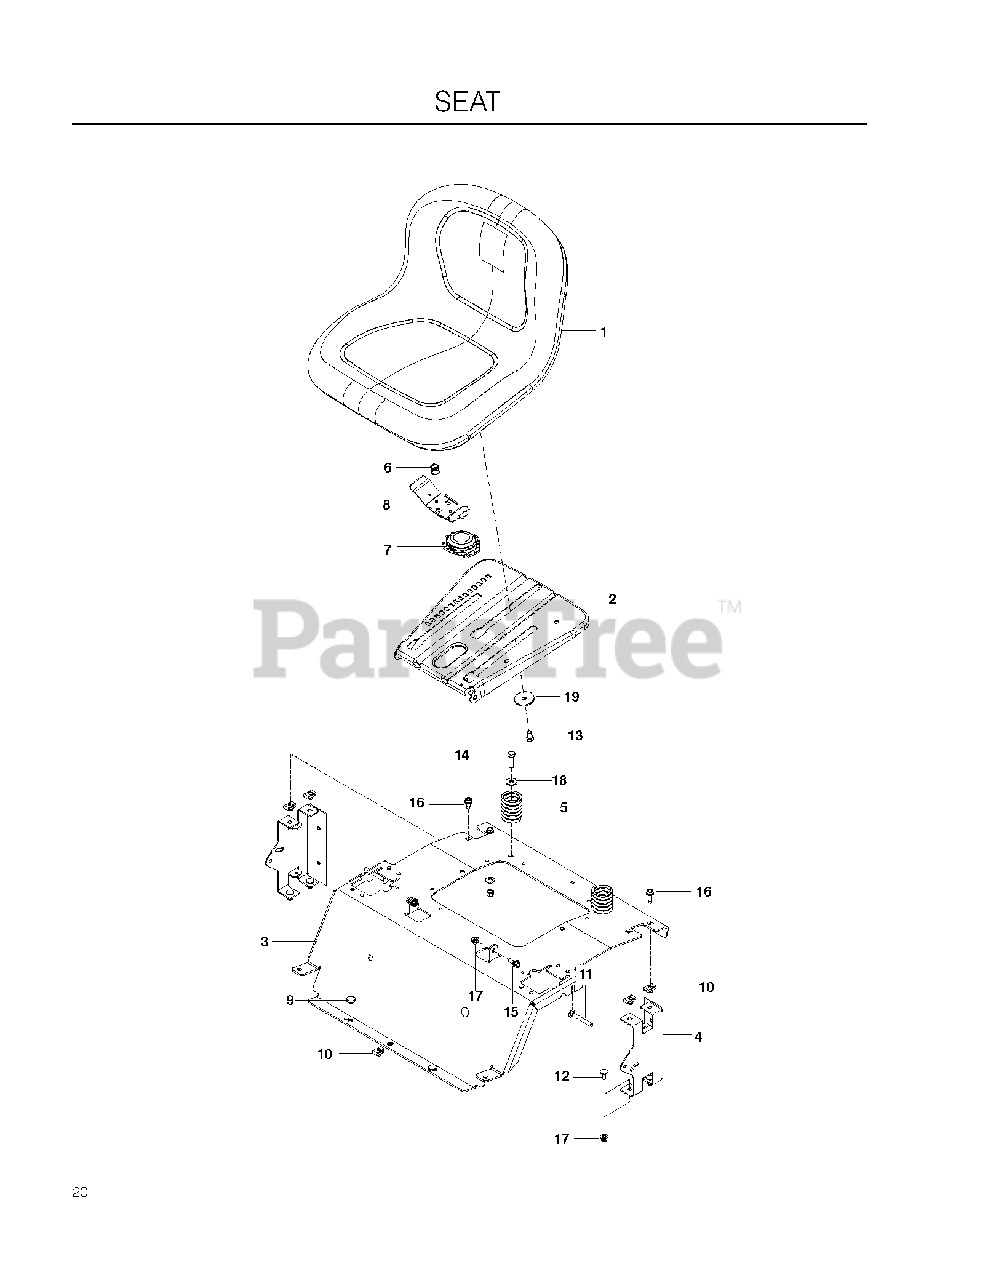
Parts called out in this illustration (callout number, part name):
1	RP SEAT, TH150, GREY, MILSCO
2	PAN.ASM.SEAT.3PT
3	SUPPORT SEAT ORANGE
4	SUPPORT, REAR SEAT, BLACK
5	SPRING, SEAT
6	SPRING.LATCH.SEAT.TEX
7	SWITCH, SEAT N/C
8	HANDLE.SLIDE.SEAT.TEX.BLACK
9	GROMMET, BUMPER
10	U-CLIP 5/16-18 NUT RETAINER
11	RHSNB 5/16-18 X 2-1/2 GR5 ZD
12	BOLT 5/16C X 3/4" CARRIAGE
13	HCS 3/8-16 X 5/8 GR 5 ZD
14	HCS 3/8C X 1 1/4 GR5
15	BOLT, SHOULDER
16	BOLT 5/16-18 X 3/4
17	5/16-18 NYLOC FLANGE NUT
18	RP WASHER 3/8 FLAT
19	WASHER, 3/8 SPEC
